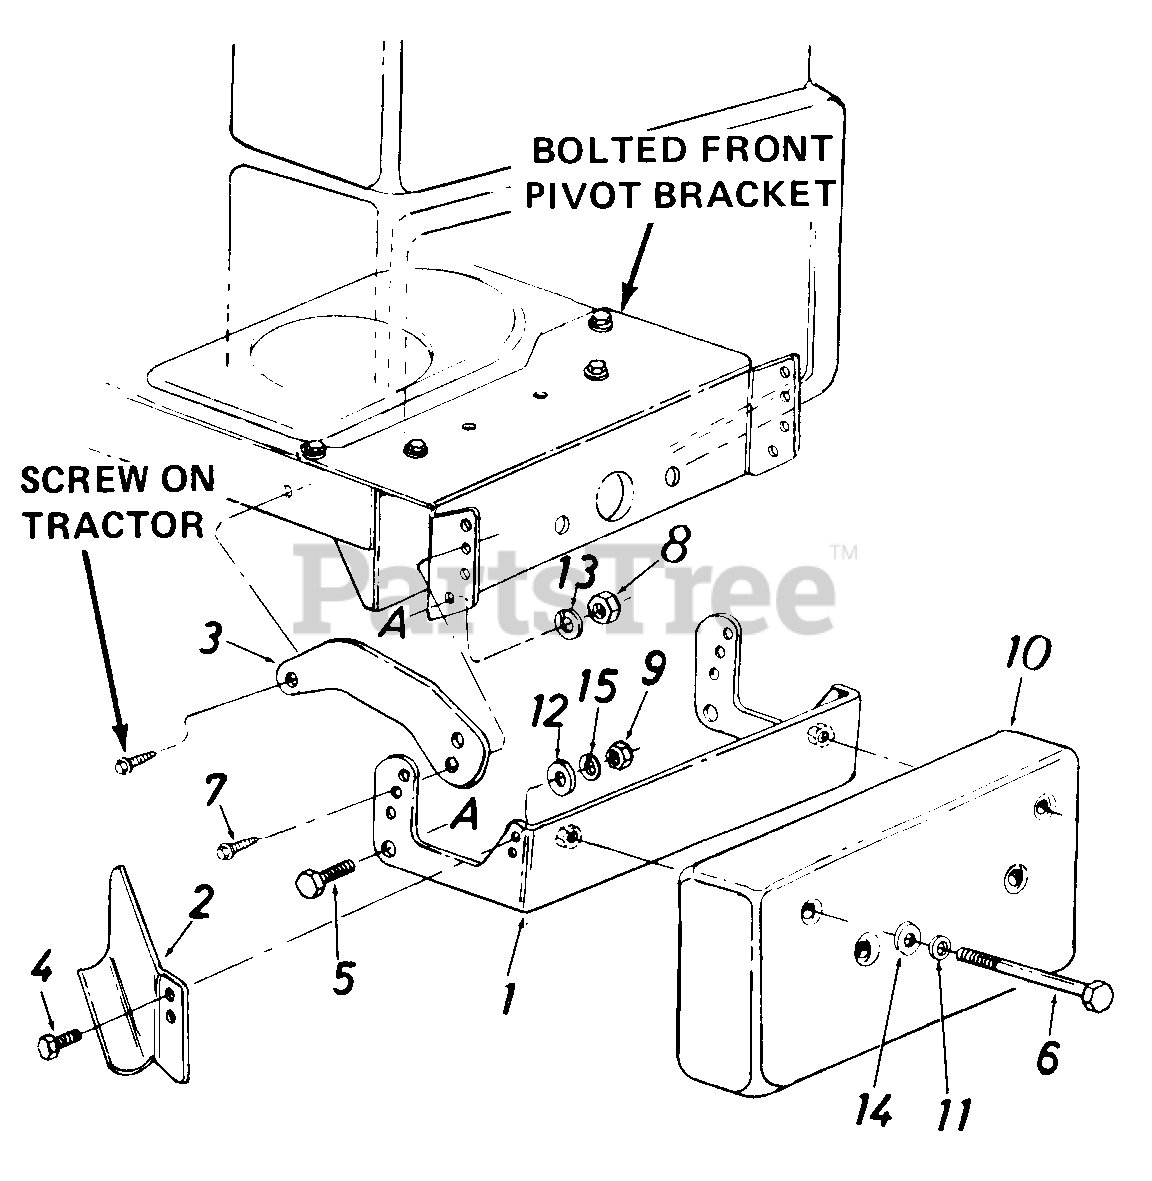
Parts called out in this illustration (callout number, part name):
1	Counterweight Bracket Ass'y.
2	Exhaust Deflector
3	Tie Strap
4	HexBoIt 1/4-20x .62" Lg.*
5	Hex Bolt 7/16-20 x 1.0" Lg.
6	Hex Bolt 3/8-16 x 4.5" Lg.
7	Hex AB 0 Tap Scr. 5/16-18 x 1.0" Lg.
8	HexJamNut7/16-20Thd.
9	Hex Nut 1/4-20 Thd. *
10	Front Counterweight-38 Lbs.
11	Bell-Wash..40" I.D. x .88" O.D.
12	Fl-Wash. .28" I.D. x .50" O.D.
13	L-Wash. 7/16" I.D.
14	Fl-Wash. .39" I.D. x 1.12" O.D.
15	L-Wash. 1/4" I.D.*
